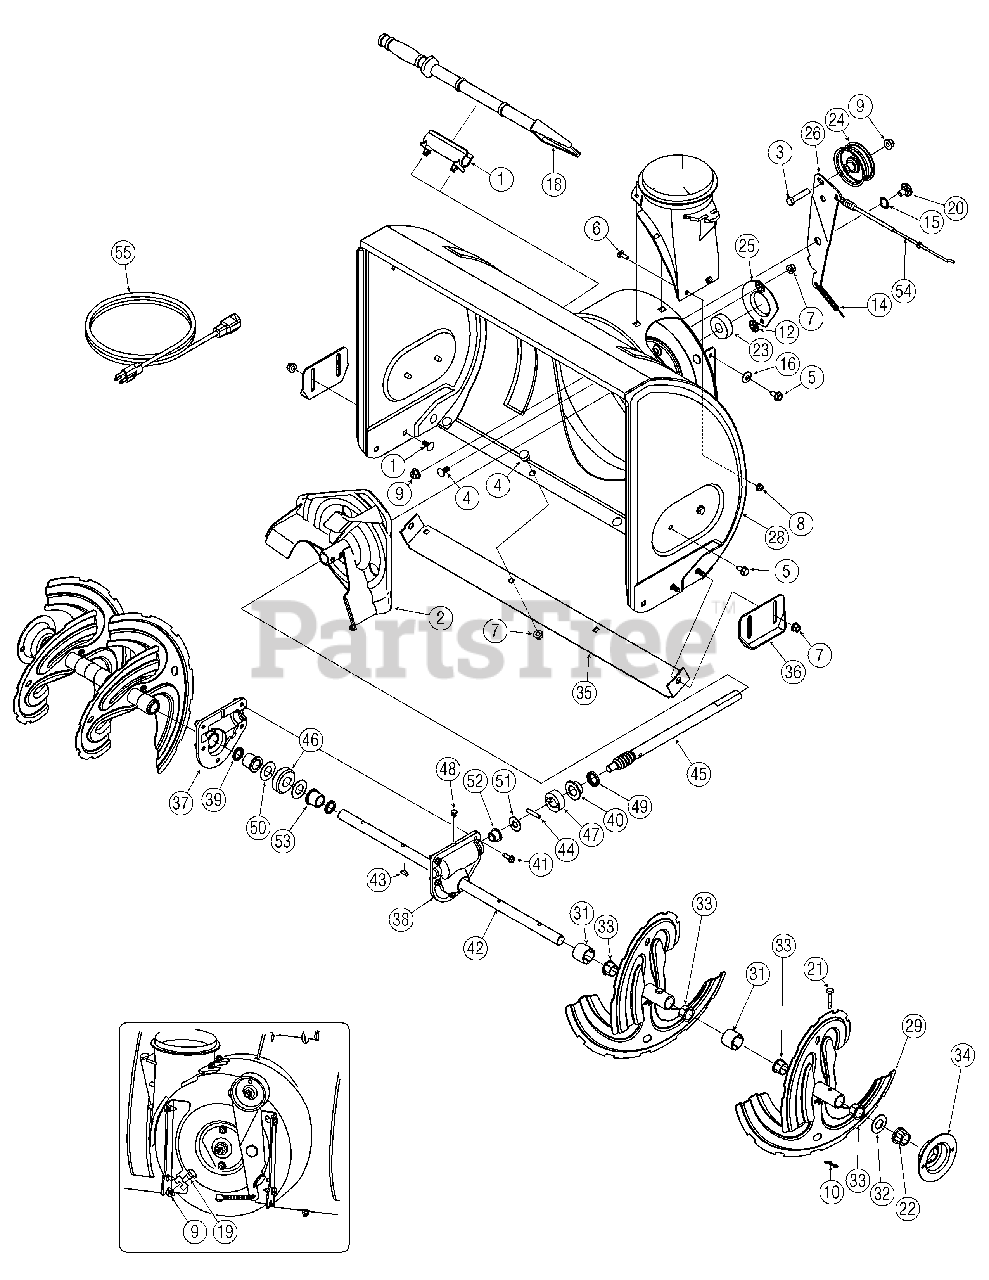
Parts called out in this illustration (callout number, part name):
1	Snow Removal Tool Mount
3	Hex Screw, 3/8-16, 1.75, Gr5
4	Bolt, Carriage, 5/16-18, .750, Gr1
5	Screw, 5/16-18, 0.625 Gr1
6	Screw, Carriage, 1/4-20, .750, Gr5
7	Nut, Flange Lock, 5/16-18, - Nylon
8	Nut, Flange Lock, 1/4-20, - Nylon
9	Nut, Flange Lock, 3/8-16, - Nylon
10	Cotter Pin, Bow-tie
11	Cable, Tie, 3/16 x .05 x 7.4
12	Nut, Push-on, .25 Dia
13	Chute, Adapter 5" Dia
14	Spring, Extension, .38 OD x 3.6
15	Washer, Wave, .625 x .885 x .015
16	Washer, Bell, .340 x .872 x.060
17	Washer, Flat, .25 x .630 x.0515
18	Snow Removal Tool
19	Screw, Shoulder, .498 x .34, 3/8-16
20	Screw, Shoulder, .625 x .17, 3/8-16
21	Shear Pin, .25 x 1.50
22	Bearing, Hex Flange x .75 ID
23	Bearing, Ball, .75 ID x 1.85 OD
24	Flat Pulley, Idler, 2.75 OD
25	Housing, Bearing, 1.85 ID
27	Gearbox Assembly, Auger, 22"
27	Gearbox Assembly, Auger, 24"
27	Gearbox Assembly, Auger, 26"
27	Gearbox Assembly, Auger, 28"
31	Spacer, 1.25 OD x .75 ID
32	Washer, Flat, .76 x 1.49 x .06
33	Bushing, Flange, .80 ID x .91OD
37	Housing, Auger, RH Reduced
38	Housing, Auger, LH Reduced
39	Seal, Oil, .750 ID
40	Bearing, Flange, .75 x 1.0 x.59
41	Screw, Self-tapping, 1/4-20, 0.750
42	Axle, Auger, 22"
42	Axle, Auger, 24"
42	Axle, Auger, 26"
42	Axle, Auger, 28"
43	Key, Hi-pro 3/16 x 5/8
44	Pin, Dowel, .25 OD x 1.2
45	Shaft, Worm .75 OD
46	Gear, Worm 20T
47	Collar, Thrust
48	Plug, 1/4 x .437
49	Seal, Oil, .75 x 1 x .131
50	Washer, Flat, .760 ID x 1.5 OD
51	Washer, Flat, .51 x 1.12
52	Bearing, Flange, .75 x 1.0 x925
53	Bearing, Flange, .75 x 1.00 x 975
54	Clutch Cable, Auger, 47.23"
55	Extension Cord, 110V
